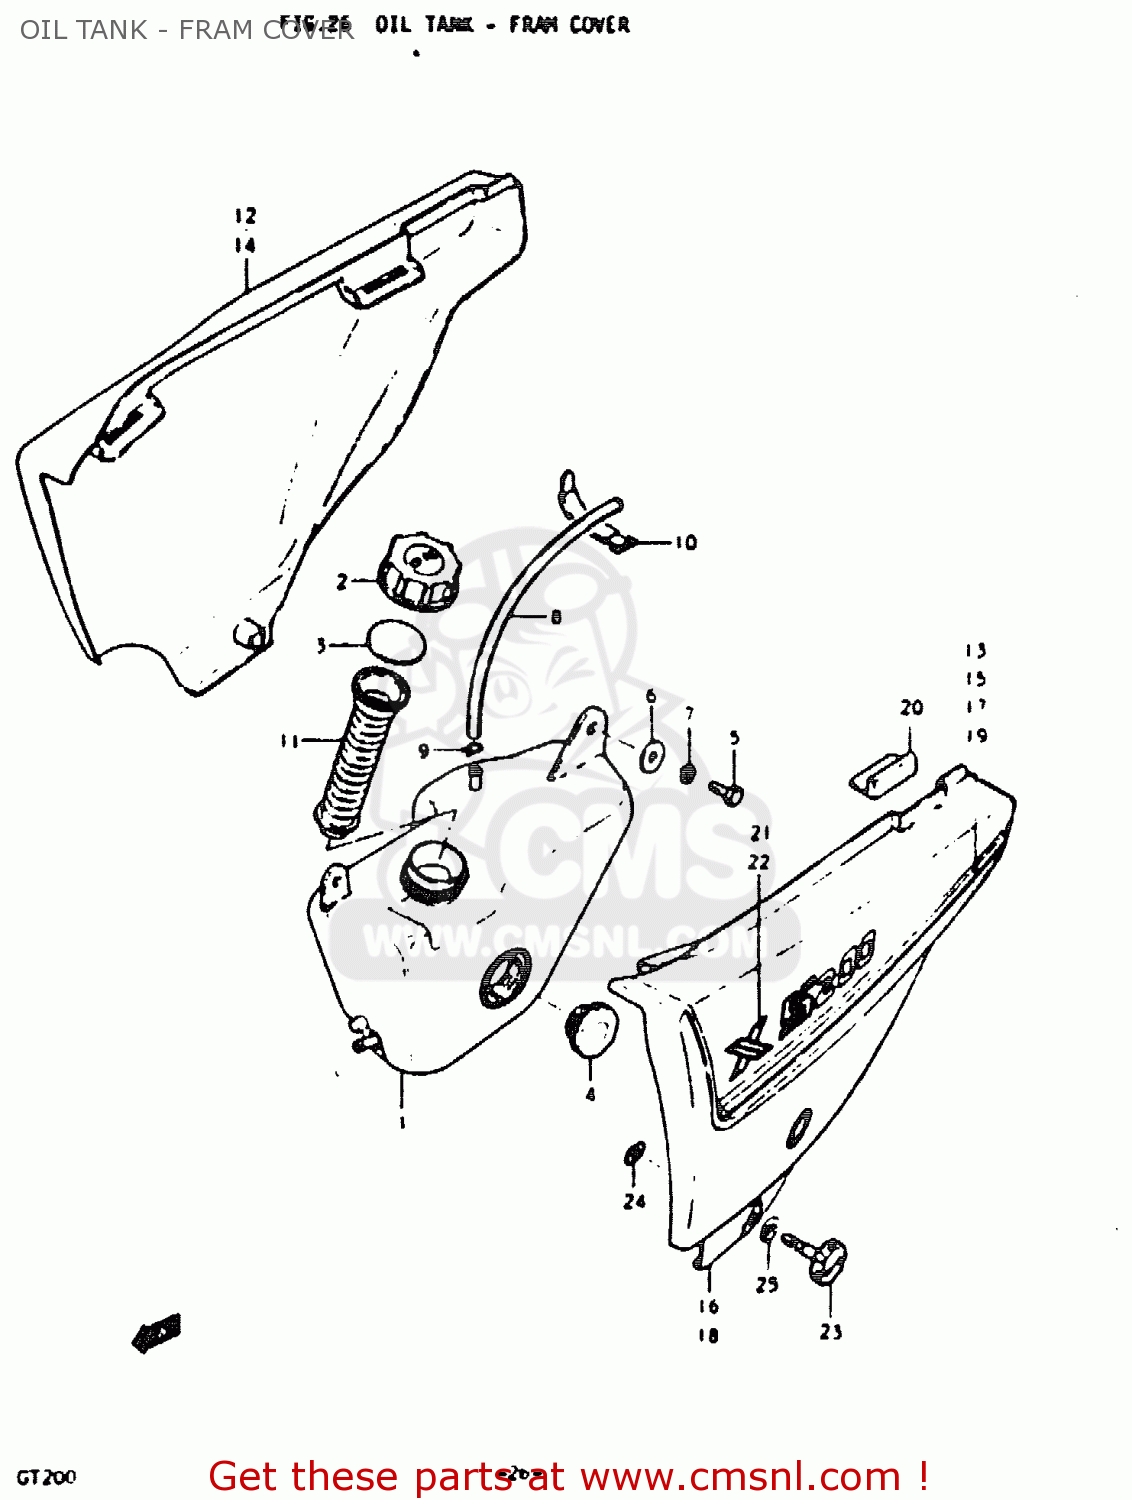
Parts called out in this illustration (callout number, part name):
1	TANK, OIL
2	CAP,OIL TANK
3	GASKET,OIL TANK CAP (NAS)
4	LENS SET,OIL LEVEL
5	BOLT
6	WASHER
7	LOCK WASHER
8	HOSE
9	CLIP
10	CLAMP
11	EXTENTION, OIL TANK INLET
12	COVER, FRAME RH
13	TAPE, RH
14	COVER, FRAME RH
15	TAPE, RH
16	COVER, FRAME LH
17	TAPE, LH
18	COVER, FRAME LH
19	TAPE, LH
20	CUSHION,FRAME COVER
21	EMBLEM, RH
22	EMBLEM, LH
23	KNOB
24	SCREW
25	WASHER
